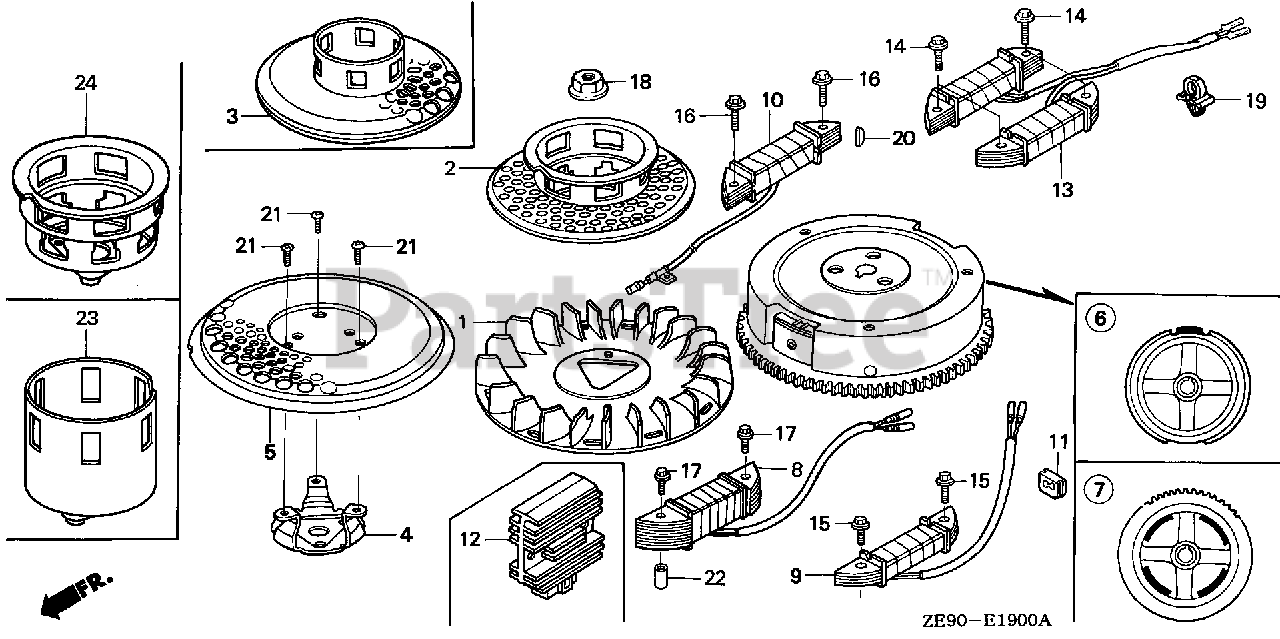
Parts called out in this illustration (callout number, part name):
1	FAN, COOLING
2	PULLEY, STARTER (NOT AVAILABLE)
3	PULLEY, STARTER (SCREEN GRID)
18	NUT, SPECIAL (16MM)
20	KEY, SPECIAL WOODRUFF (25X18)
